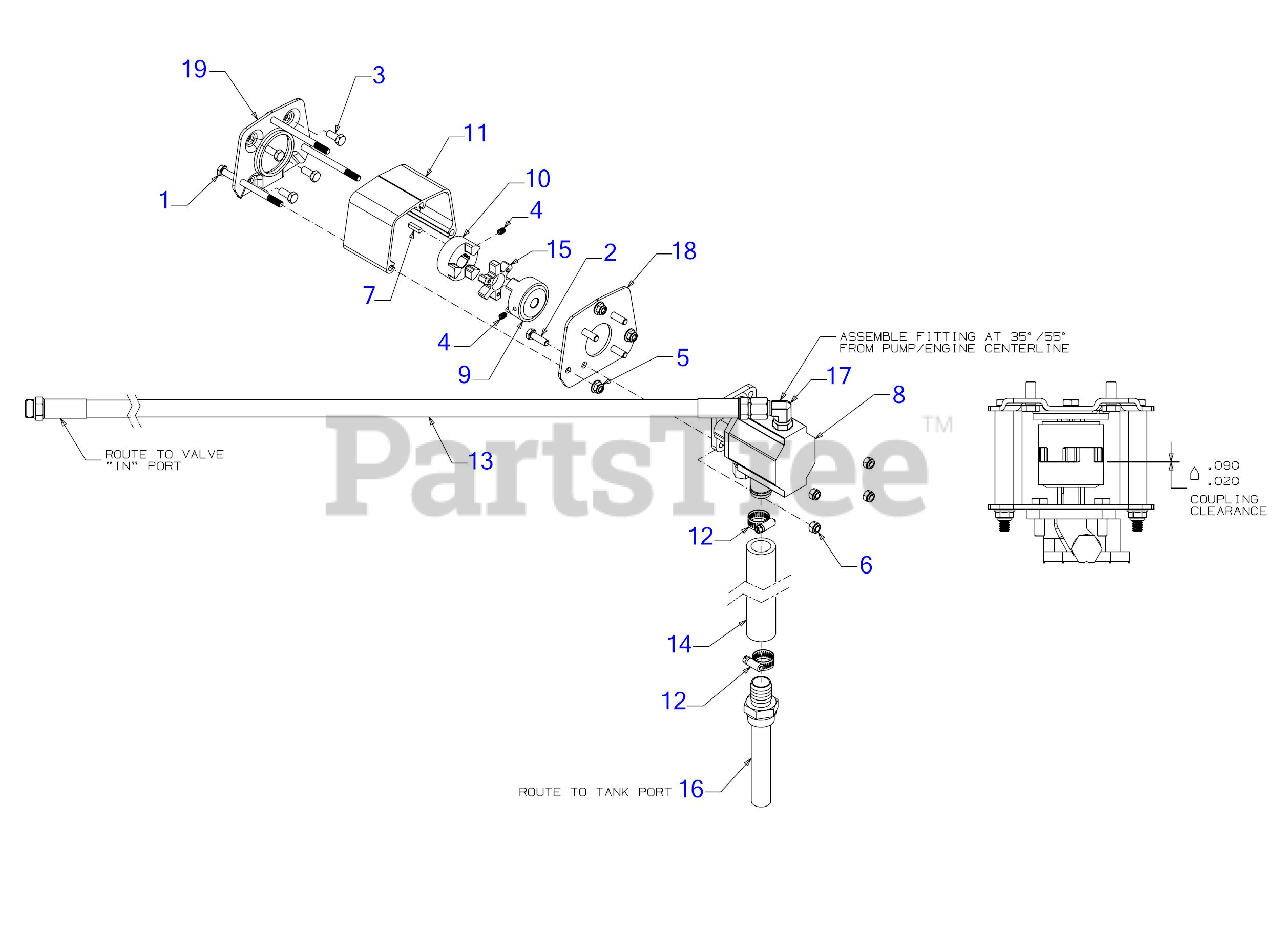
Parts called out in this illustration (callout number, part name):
1	HEX SCREW 5/16-18 x 4.00
2	SCREW 5/16-18 x 1.0 GR5
3	SCREW 5/16-24 x .750 GR5
4	SCREW 1/4-20 x .38
5	FLANGE LOCK NUT 5/16-18
6	HEX NUT
7	SQUARE KEY 3/16 x .7
8	LOGSPLITTER GEAR PUMP 11GPM
9	LOGSPLITTER COUPLING .500
10	LOGSPLITTER COUPLING .750
11	COUPLING SHIELD
12	HOSE CLAMP-5/8
13	48" HYDRAULIC HOSE
14	INPUT HOSE
15	SPIDER COUPLING BUSHING
16	INLET FILTER
17	HYDRAULIC FITTING
18	SUPPORT BRACKET
